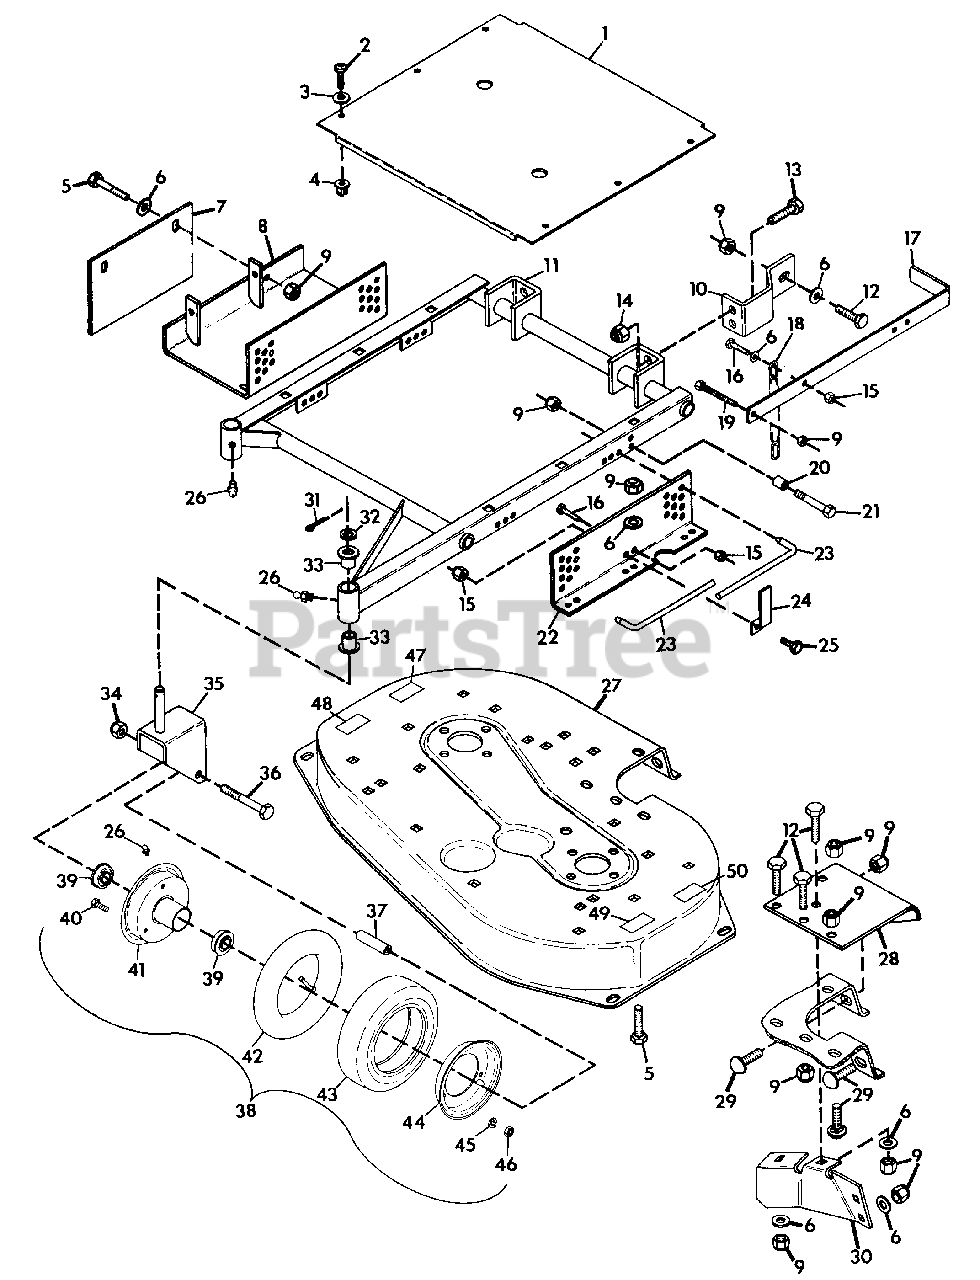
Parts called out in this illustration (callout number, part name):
1	GUARD, 40" MOWER BELT
2	SCREW, TAPPING 1/4-20X.50 P/HD
3	WASHER, FLAT .281X.625X.065
4	GROMMET, PLASTIC
5	BOLT, HEX 3/8-16X1.00
6	WASHER, FLAT .406X.812X.065
7	PLATE, DISCHARGE COVER
8	WELDMENT, MOWER SUPPORT
9	NUT, LOCK 3/8-16
10	BRACE, PRO L.H.
10	BRACE, PRO R.H.
11	WELDMENT, FRAME SUPPORT
12	BOLT, HEX 3/8-16X1.25
13	BOLT, HEX 1/2-13X1.50
14	NUT, LOCK 1/2-13
15	NUT, LOCK 5/16-18
16	BOLT, HEX 5/16-18X1.00
17	BAR, LIFT
18	CHAIN, HEIGHT ADJUSTMENT
19	BOLT, HEX 3/8-16X2.00
20	BUSHING .391X.622X.670
21	BOLT, HEX 3/8-16X1.50
22	BRACKET, MOWER SUPPORT
23	PIN, MOWER LOCKING
24	TAB, PIN LOCKING
25	BOLT, HEX 5/16-18X.75
26	FITTING, LUBE 1/4-28
27	DECK, 40" MOWER
28	SHIELD, DISCHARGE
29	BOLT, 3/8-16X1.00 RD HD SQ NK
30	SHROUD, BLADE
31	PIN, COTTER .187X1.50
32	RACE, BEARING THRUST
33	BUSHING, PIVOT
34	NUT, LOCK 1/2-13
35	WELDMENT, CASTER FORK
36	BOLT, HEX 1/2-13X5.00
37	BUSHING, WHEEL .520X.750X3.312
38	WHEEL, GAUGE
39	BEARING, GAUGE WHEEL
40	BOLT, HEX 3/8-24X.75
41	WHEEL, HALF WITH TUBE
42	TUBE, INNER
43	TIRE, GAUGE WHEEL
44	WHEEL, HALF PLAIN
45	WASHER, LOCK 3/8 SP HEAVY
46	NUT, HEX 3/8-24
47	DECAL, CAUTION
48	DECAL, DANGER FOOT
49	DECAL, DANGER HAND
50	DECAL, WARNING EYE
NS	DECAL, GRAVELY LOGO
NS	DECAL, PRO-40
NS	DECAL, AMERICA
